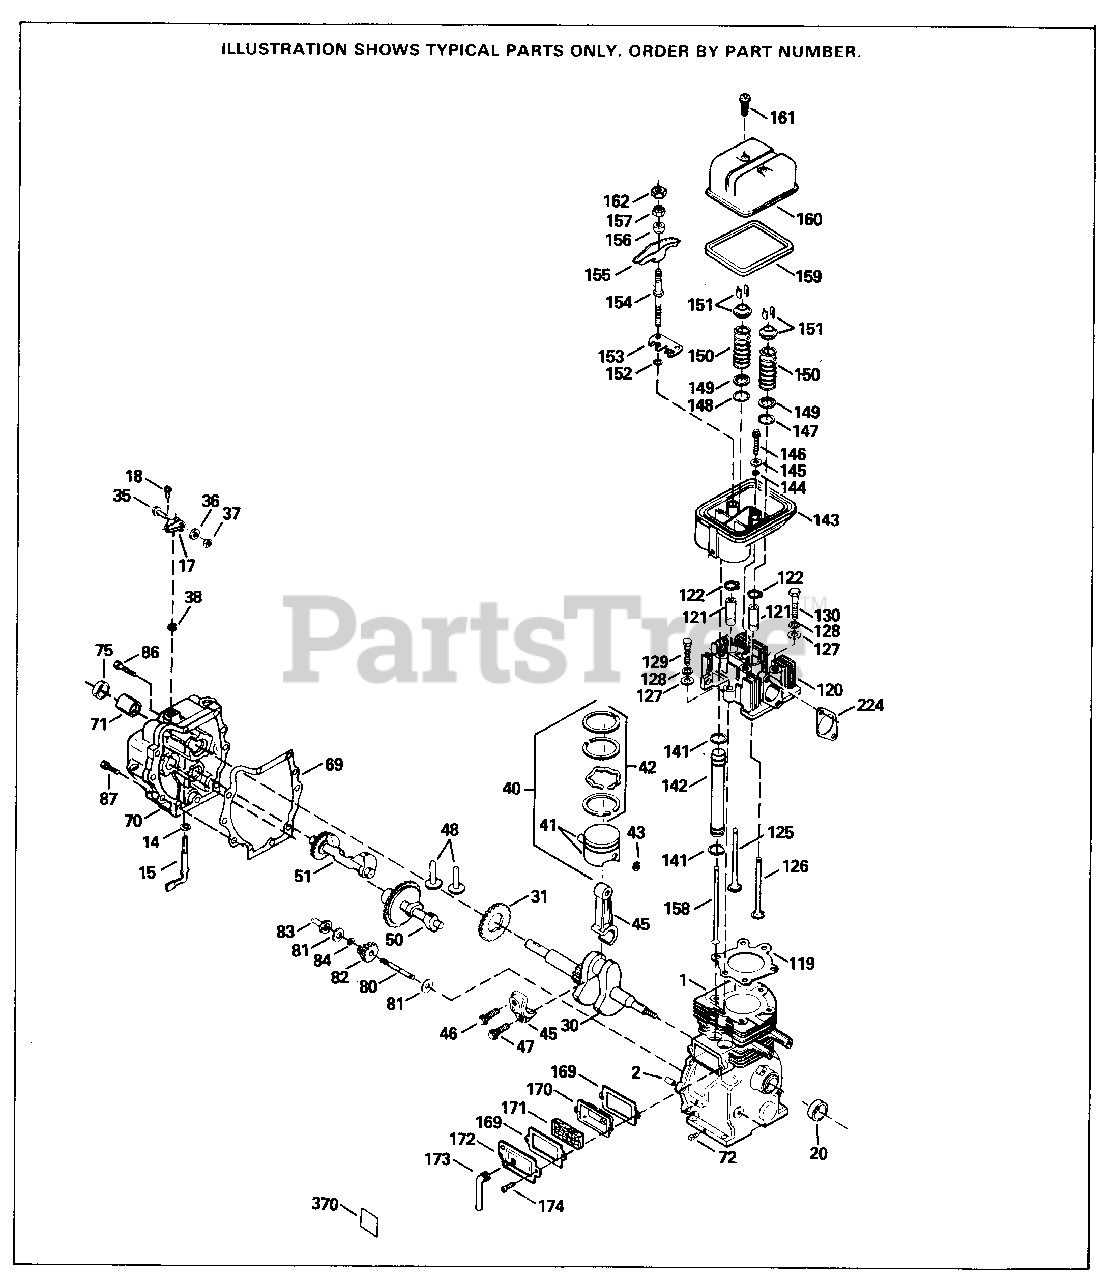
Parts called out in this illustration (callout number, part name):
1	"Cylinder (Incl. 2, 20, 72 & 80)
2	Dowel Pin
14	Flat Washer
15	Governor Rod (Incl. 14 & 38)
15A	Governor Yoke
15B	Screw, 6-40 x 5/16"
17	Governor Lever Clamp
20	Oil Seal
30	Crankshaft
31	Counterbalance Gear
35	Screw, 10-32 x 3/4"
37	Lock Nut, 10-32
38	Retaining Ring
40	Piston, Pin & Ring Set (Std) (Incl. 4 1, 42 & 43)
40	Piston, Pin & Ring Set (.010" OS) (In cl. 41, 42 & 43)
40	Piston, Pin & Ring Set (.020" OS) (In cl. 41, 42 & 43)
41	Piston & Pin Assembly (Std) (Incl. 43 )
41	Piston & Pin Ass'y. (.010" OS) (Incl. 43)
41	Piston & Pin Ass'y. (.020" OS) (Incl. 43)
42	Ring Set (Std.) (3-5/16")
42	Ring Set (.010" OS)
42	Ring Set (.020" OS)
43	Piston Pin Retaining Ring
45	Connecting Rod Ass'y. (Incl. 47)
47	Connecting Rod Bolt
48	Valve Lifter
50	Camshaft (MCR)
51	Counterbalance Weight
69	Cylinder Cover Gasket
70	Cylinder Cover (Incl. 14, 15, 38, 71 & 75) 5)
71	Crankshaft Bushing
72	Oil Drain Plug (Sq. hd., 1/4-18)
75	Oil Seal
80	Governor Shaft
81	WASHER
82	Governor Gear Assembly
83	Governor Spool
84	Retaining Ring
86	Screw, 1/4-20 x 1-3/16"
87	Screw, 1/4-20 x 1-11/16"
119	Cylinder Head Gasket
159	Rocker Arm Cover Gasket
169	Valve Cover Gasket
170	Breather Body
171	Breather Element
172	Valve Cover
173	Breather Tube
174	Screw, 10-24 x 1/2"
184	Carburetor To Intake Pipe Gasket
224	Intake Pipe Gasket
269	Exhaust Manifold Gasket
370A	Lubrication Decal
